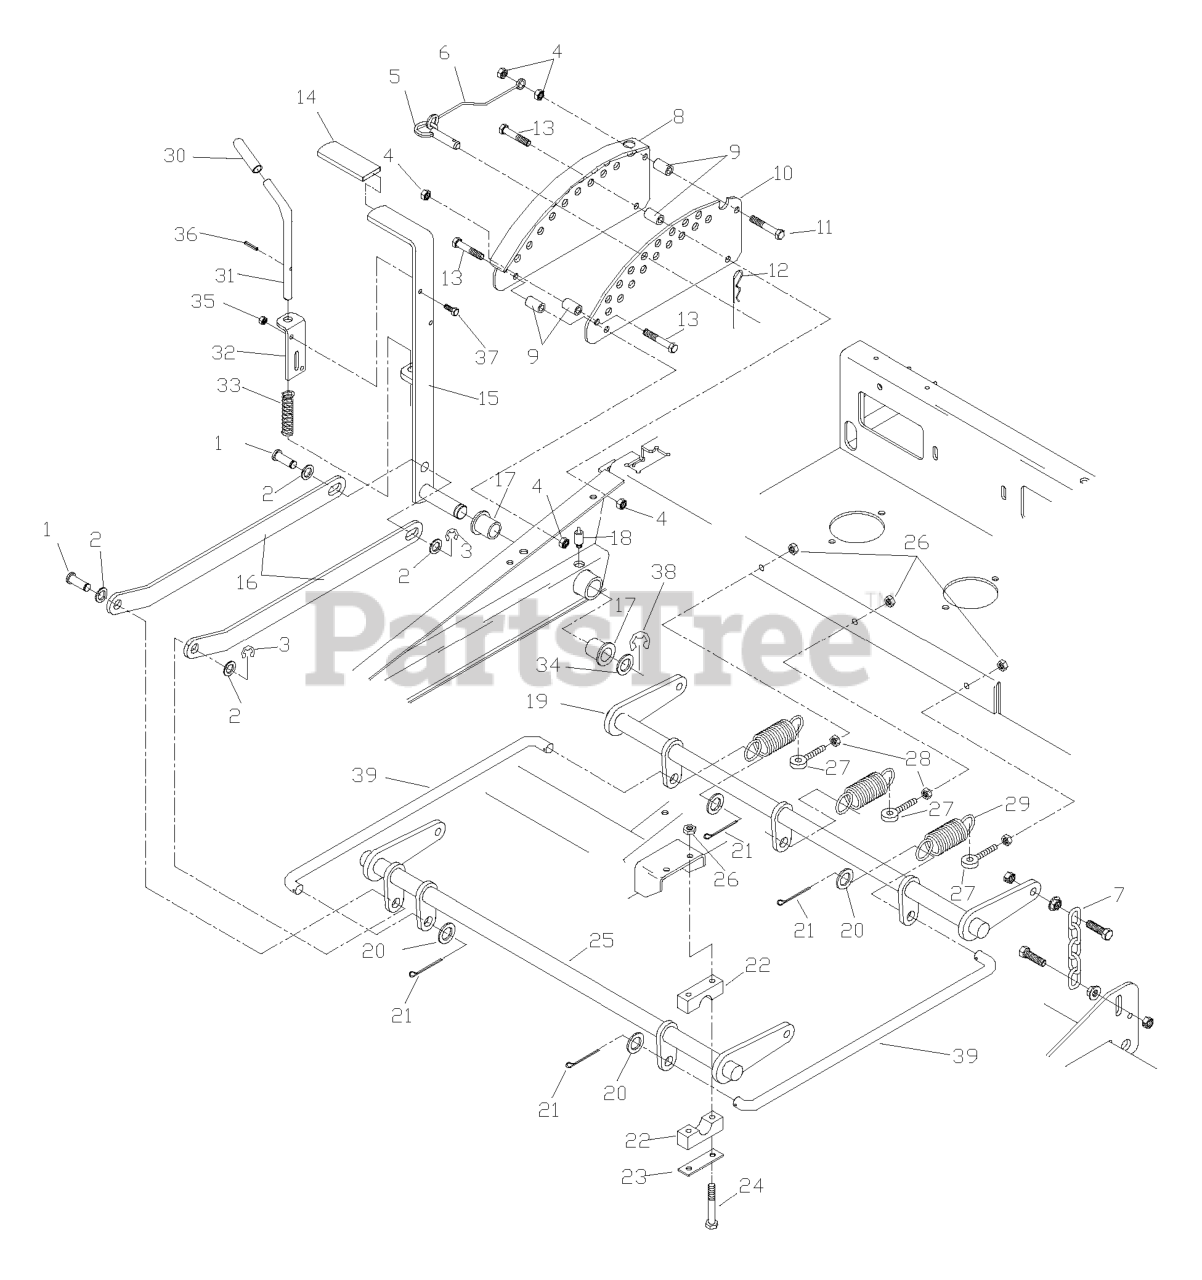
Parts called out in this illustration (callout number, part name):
1	CLEVIS PIN
3	E-RING 5/8
4	NUT 3/8C CENTERBLOCK
7	LIFT CHAIN
8	ADJ. PLATE WLDMNT
9	DECK LIFT SPACER
10	ADJ. PLATE PAINTED
11	HCS 3/8C X 2 1/2
12	HAIRPIN #4
13	HCS 3/8C X 2 1/4
15	LIFT LEVER WLDMT
16	LIFT LINKAGE,PAINTED
17	BUSHING, FLANGED
18	GREASE ZERK LONG
19	LIFT SHAFT
20	WASHER 5/8 FLAT
21	COTTER PIN
22	PILLOW BLOCK
23	REINFORCEMENT BAR
24	BOLT 5/16C X 2 1/2
25	FT. LIFT SHAFT
26	NUT 5/16C CENTERLOCK
27	EYEBOLT, RH
28	NUT 5/16C WHIZ
29	DECK LIFT SPRING
32	PIN MT, UPPER
34	BSHG .875 X 1.375 X .074 ZD
35	NUT 1/4C CENTER LOCK
36	ROLL PIN 3/16 X 1-1/4 ZD
37	HCS 1/4C X 3/4 HCS
38	E-RING 7/8
39	CONNECTING LINK
